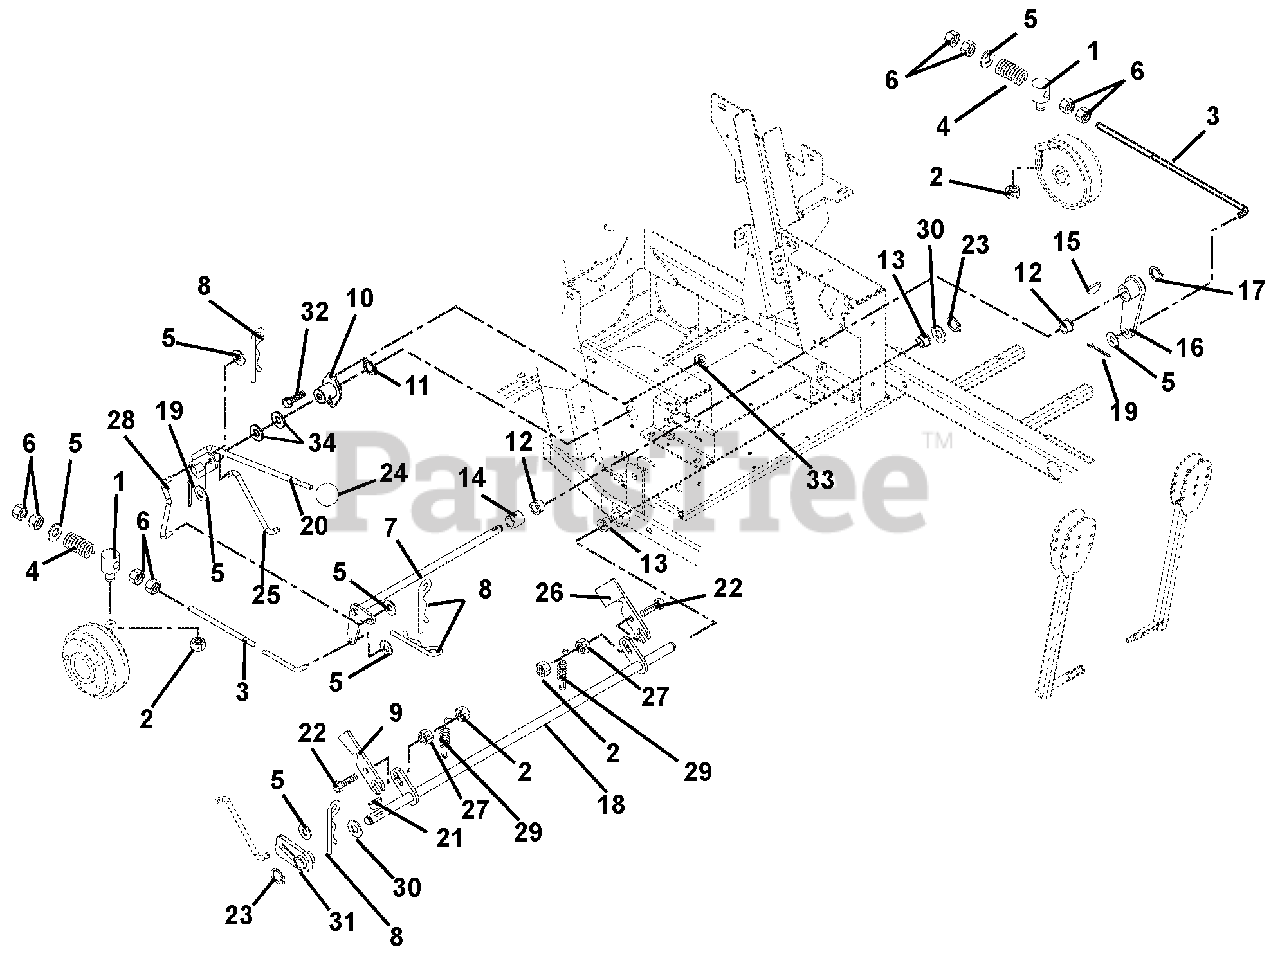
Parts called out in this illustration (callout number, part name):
1	PIN, PIVOT/TRUNNION
2	@NUT-LK-CTR .31-18 YWZC
3	PTO LINK ROD, PRO-150
4	SG-COMP .142 X .710 X 1.75
5	@WSHR-FL-STL.406X.812X.065 YWZ
6	@NUT-HEX .38-16 YWZC
7	WMT, BRAKE CROSS SHAFT
8	PIN-HAIR, ENDRIES #25 YWZC
9	SLIDE, INTERLOCKING BRAKE
10	BUSHING, FLANGED
11	RG-RTNG-EXT .625X.050
12	BSHG-FLG .762X1.0X.580X1.48 NY
13	BSHG-FLG .515X.750X.745X1.00NY
14	BSHG-SLV .750X1.000X.750
15	KEY-WDRF .19X.75 HRD #9
16	WMT, BRAKE ARM
17	RG-RTNG-EXT .689X.078
18	WMT, MECHANICAL BRAKE
19	@PIN-CTR .09X.75 EXTPRSQCT YWZ
20	WMT, BRAKE ACTUATING LEVER
21	KEY-WDRF .13X.63 HRD#5
22	@BLT-RDHDSQNK .31-18X1.25 G5YZ
23	RG-RTNG-EXT .500X.050 (SNAP)
24	KNOB-STEERING LOCK
25	LINKAGE, BRAKE ACTUATING
26	INTERLOCK, SAFETY SWITCH
27	@NUT-LK-TOP-FLG .31-18 YWZC
28	LINKAGE, BRAKE ACTUATING
29	SG-TENS .063X.44X1.56
30	WSHR-FL-STL .505X1.00X.062YWZC
31	WMT, PARKING BRAKE HUB
32	@BLT-HEX .31-18X.75 GR5 YWZC
33	@NUT-LK-TOP-FLG .31-18 YWZC
34	WSHR-FL-STL .630X1.250X.062 YZ
